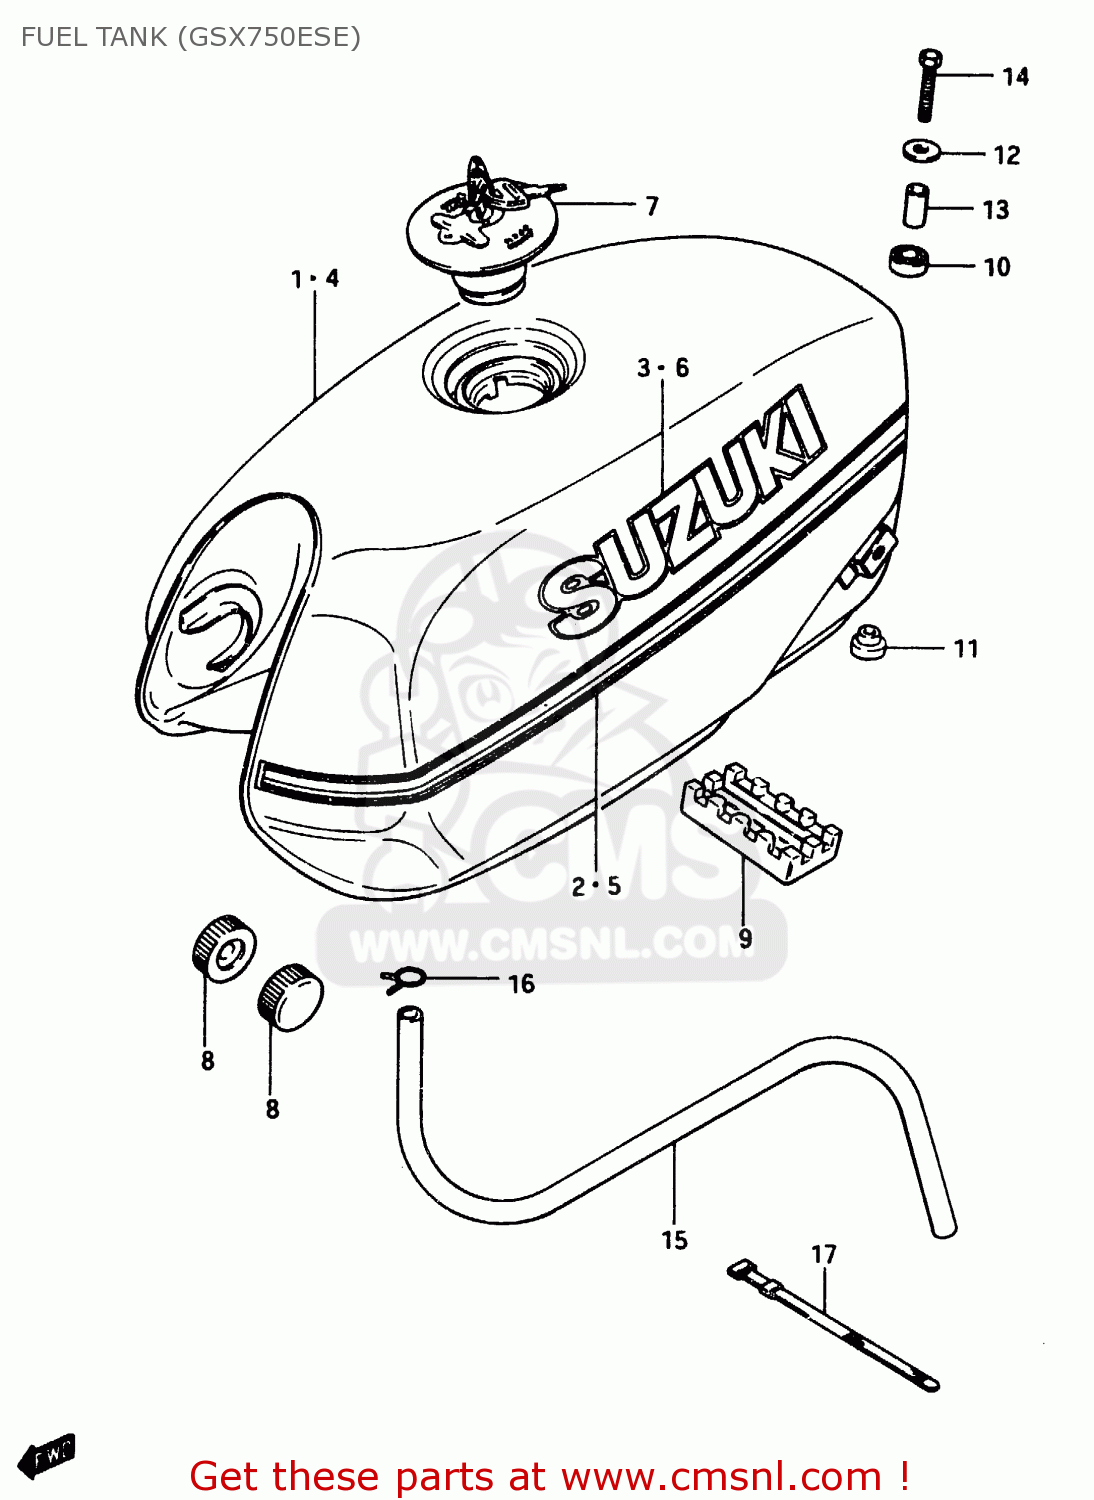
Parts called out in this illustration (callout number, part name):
1	TANK,FUEL
2	TAPE SET, FUEL TANK
3	EMBLEM
4	TANK, FUEL
5	TAPE SET, FUEL TANK
6	EMBLEM
7	CAP, FILLER
8	CUSHION
9	CUSHION,FUEL TANK CTR
10	CUSHION
11	CUSHION
12	WASHER (6.5X24X1.6)
13	SPACER
14	BOLT
15	HOSE,FUEL
16	CLIP
17	CLAMP(L:187)
